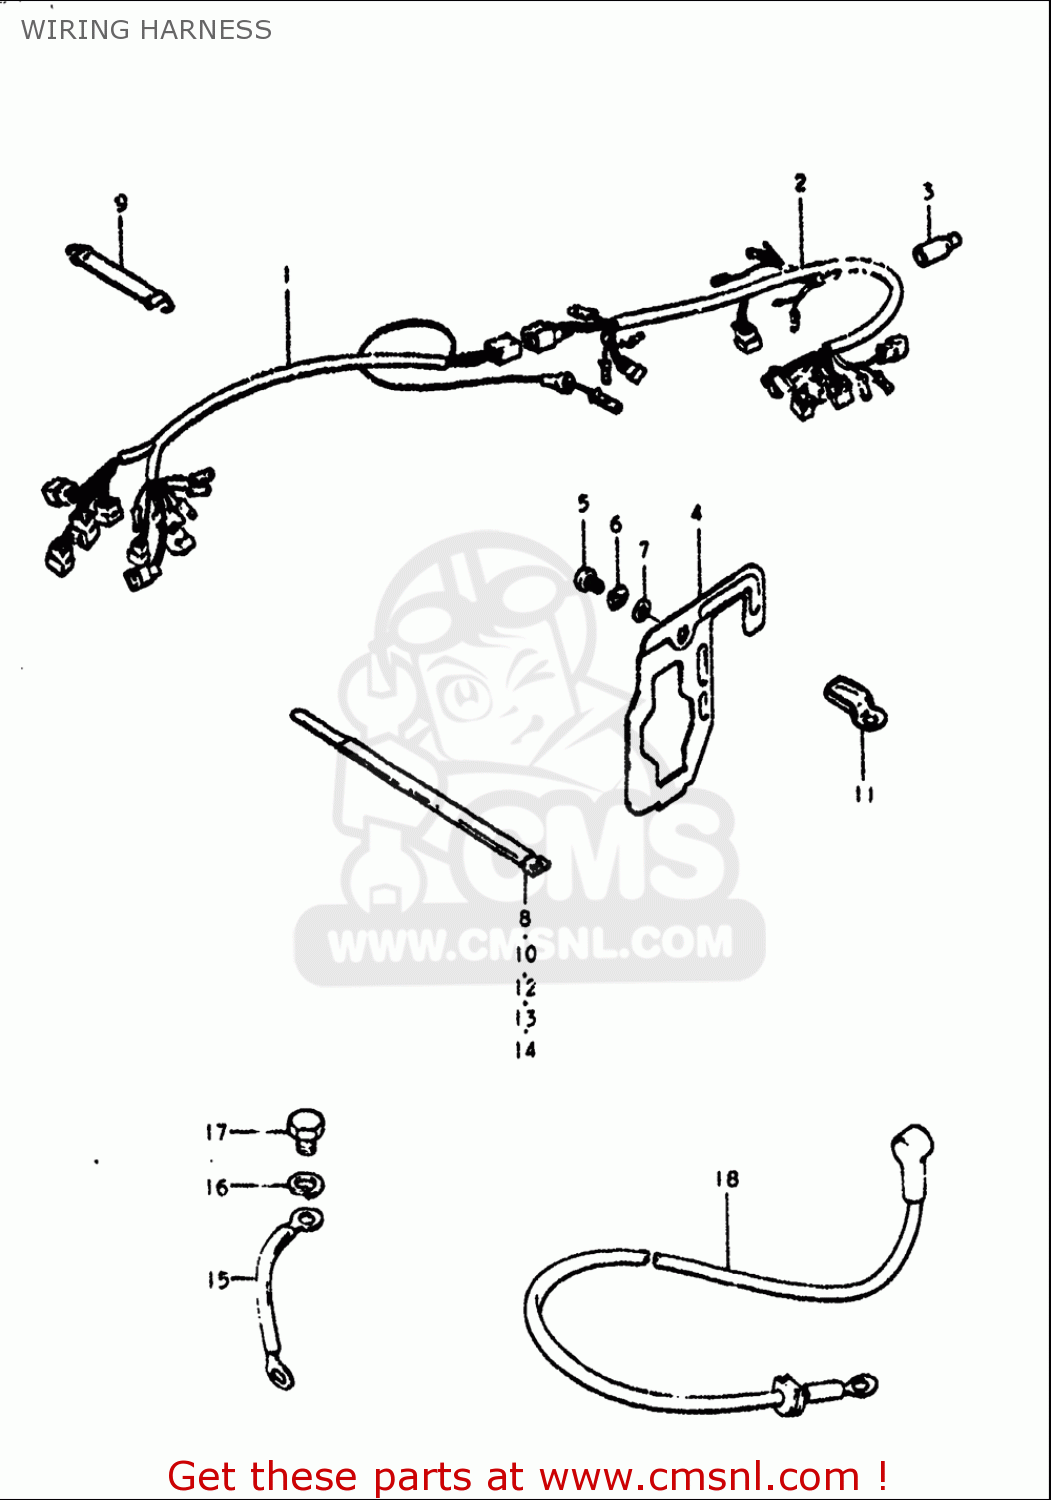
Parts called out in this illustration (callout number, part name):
2	HARNESS,WIRING NO.2
3	BOOT,WIRING HARNESS
5	SCREW
6	WASHER,LOCK
7	WASHER
8	CLAMP
10	CLAMP
11	CLAMP
12	CLAMP
13	CLAMP
14	CLAMP
16	WASHER,LOCK
17	BOLT
